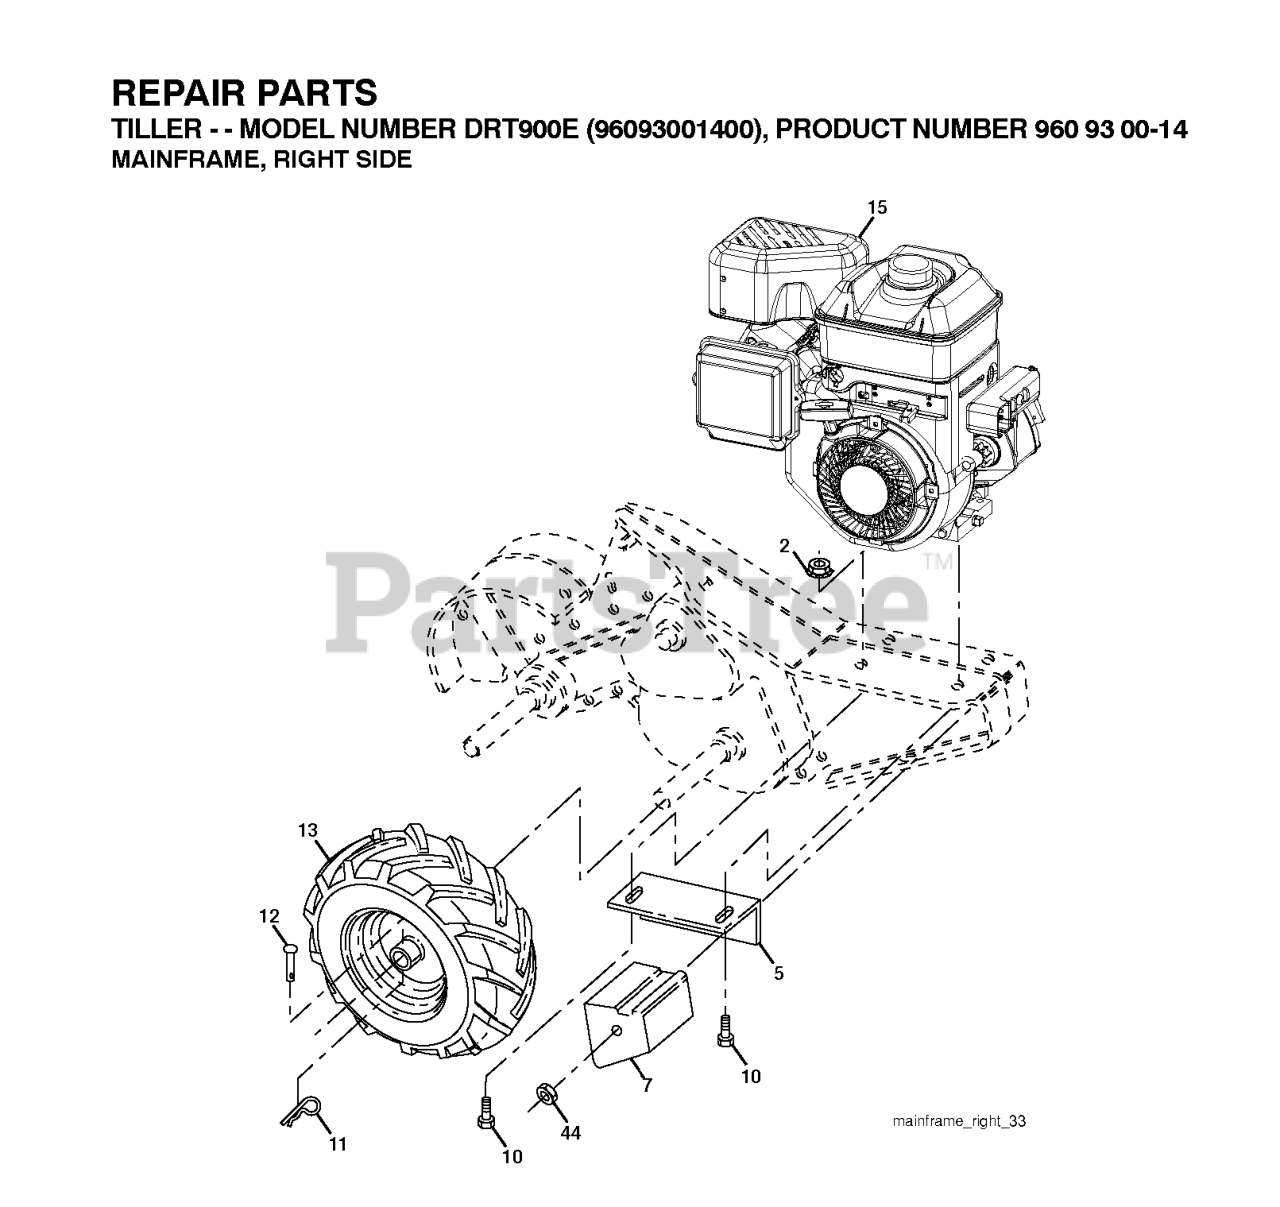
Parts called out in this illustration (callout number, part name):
2	LOCKNUT-FLANGE 5/16-18
5	DNO BRACKET RH CRT
7	COUNTERWEIGHT, RH
10	BOLT
11	RETAINER M
12	RIVET,DRILLED
13	TIRE.13X5-6.CHEVRON.TILLER
